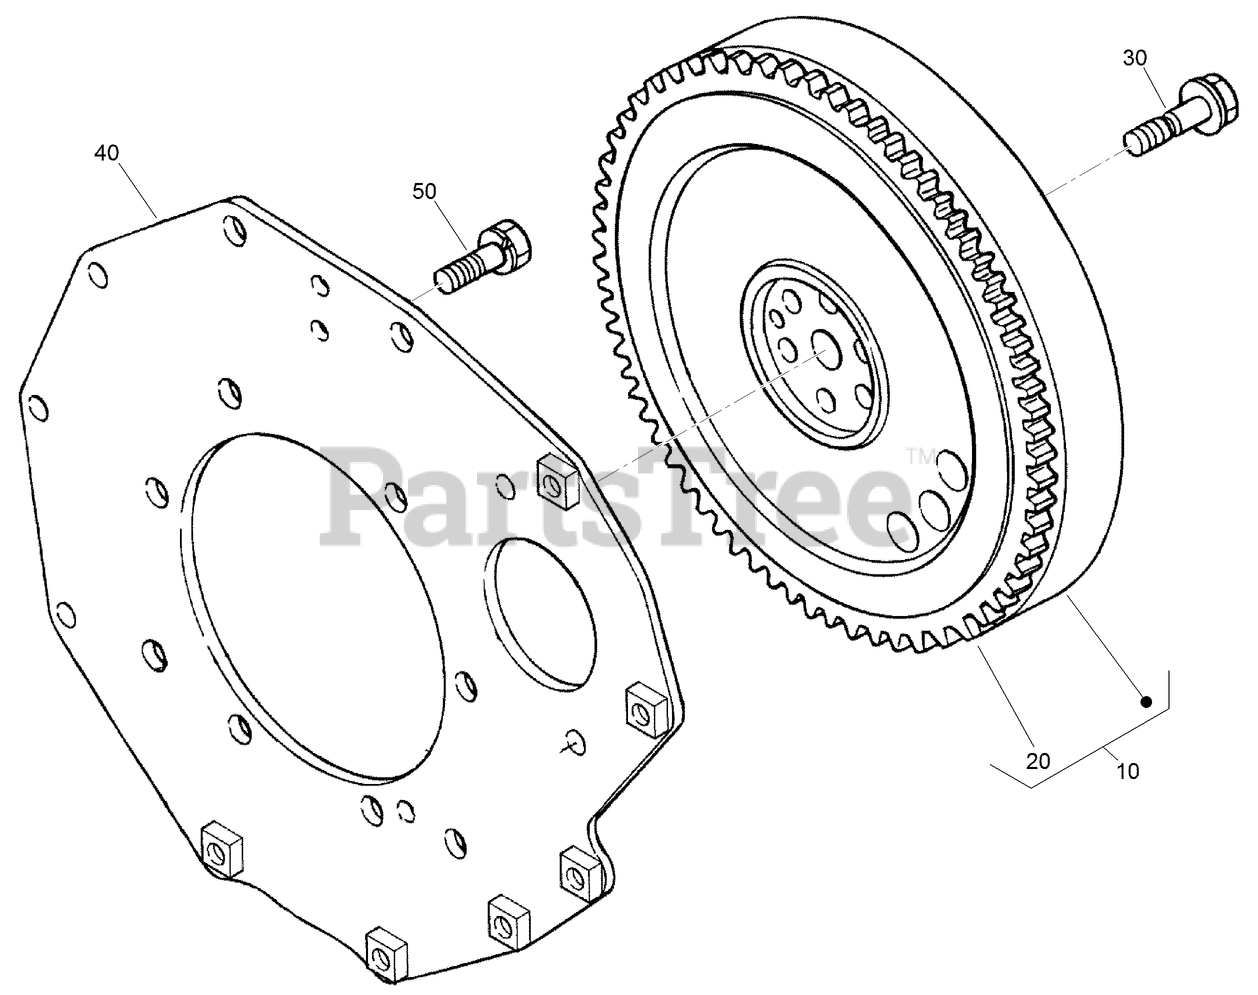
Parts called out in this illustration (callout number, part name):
10	FLYWHEEL ASM
20	GEAR-RING
30	BOLT-FLYWHEEL
40	PLATE-END, REAR
